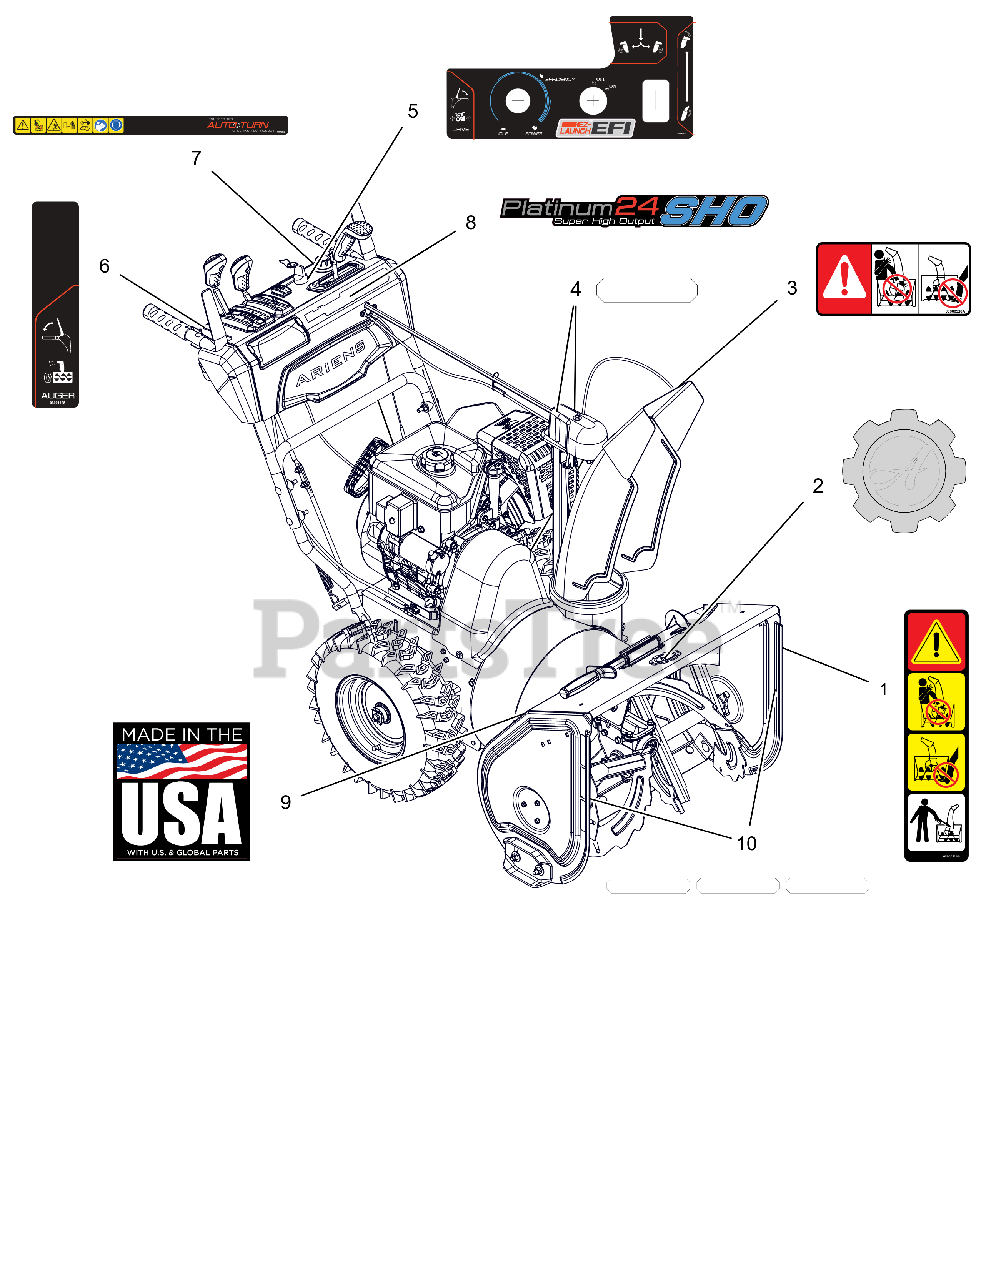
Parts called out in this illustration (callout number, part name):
1	DECAL, DANGER - ROTATING PARTS
2	DECAL, ARIENS-GEAR BADGE -THK
3	DECAL, DANGER
4	DECAL,REFLECTIVE,GEAR COVER
5	DECAL, CONTROL - QT EFI W/GEL
6	DECAL,CONTROL-RH CONTROL
7	DECAL,DASH - SAFETY/EFI
8	DECAL, DASH, PLATINUM 24 SHO
9	DECAL, MADE IN USA
10	DECAL,REFLECTIVE,HOUSING
